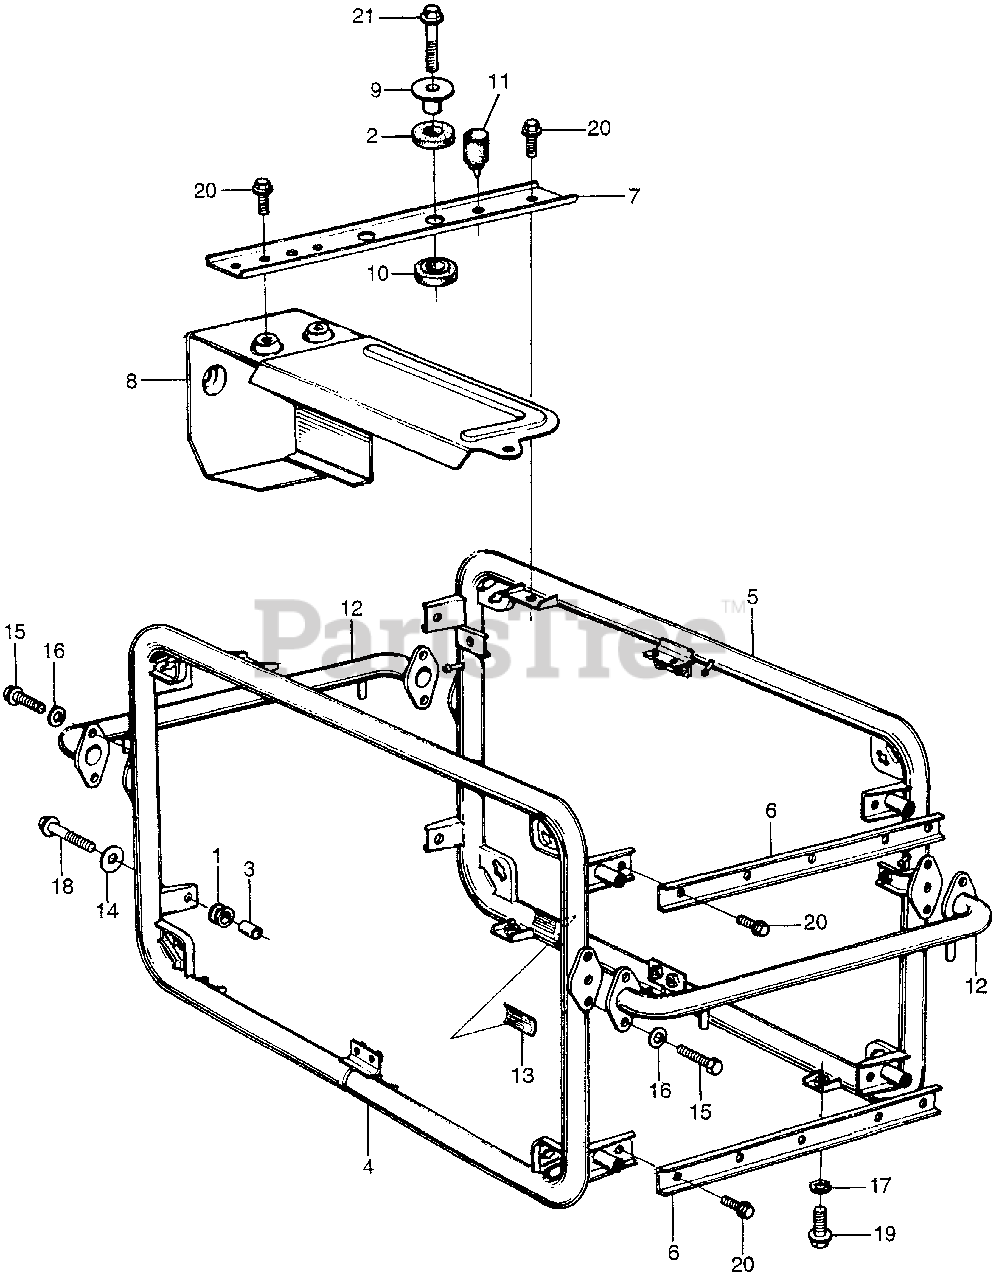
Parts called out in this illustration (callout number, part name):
1	RUBBER, AIR CLEANER HOUSING SETTING
2	RUBBER, FUEL TANK SETTING
3	COLLAR, RR. TURN SIGNAL STAY
4	FRAME, L. PIPE
5	FRAME, R. PIPE
7	SUPPORT, CONTROL BOX
8	SEPARATOR, MUFFLER
9	COLLAR, RUBBER MOUNT
10	RUBBER, CONTROL BOX MOUNT
11	RUBBER, CUSHION
13	MARK, TOOL
14	WASHER, WHEEL (6MM)
15	BOLT, HEX. (6X20)
16	WASHER, PLAIN (6MM)
17	WASHER, SPRING (8MM)
18	BOLT, FLANGE (6X25)
19	BOLT, FLANGE (8X16)
20	BOLT, FLANGE (6X12)
21	BOLT, FLANGE (8X32)
